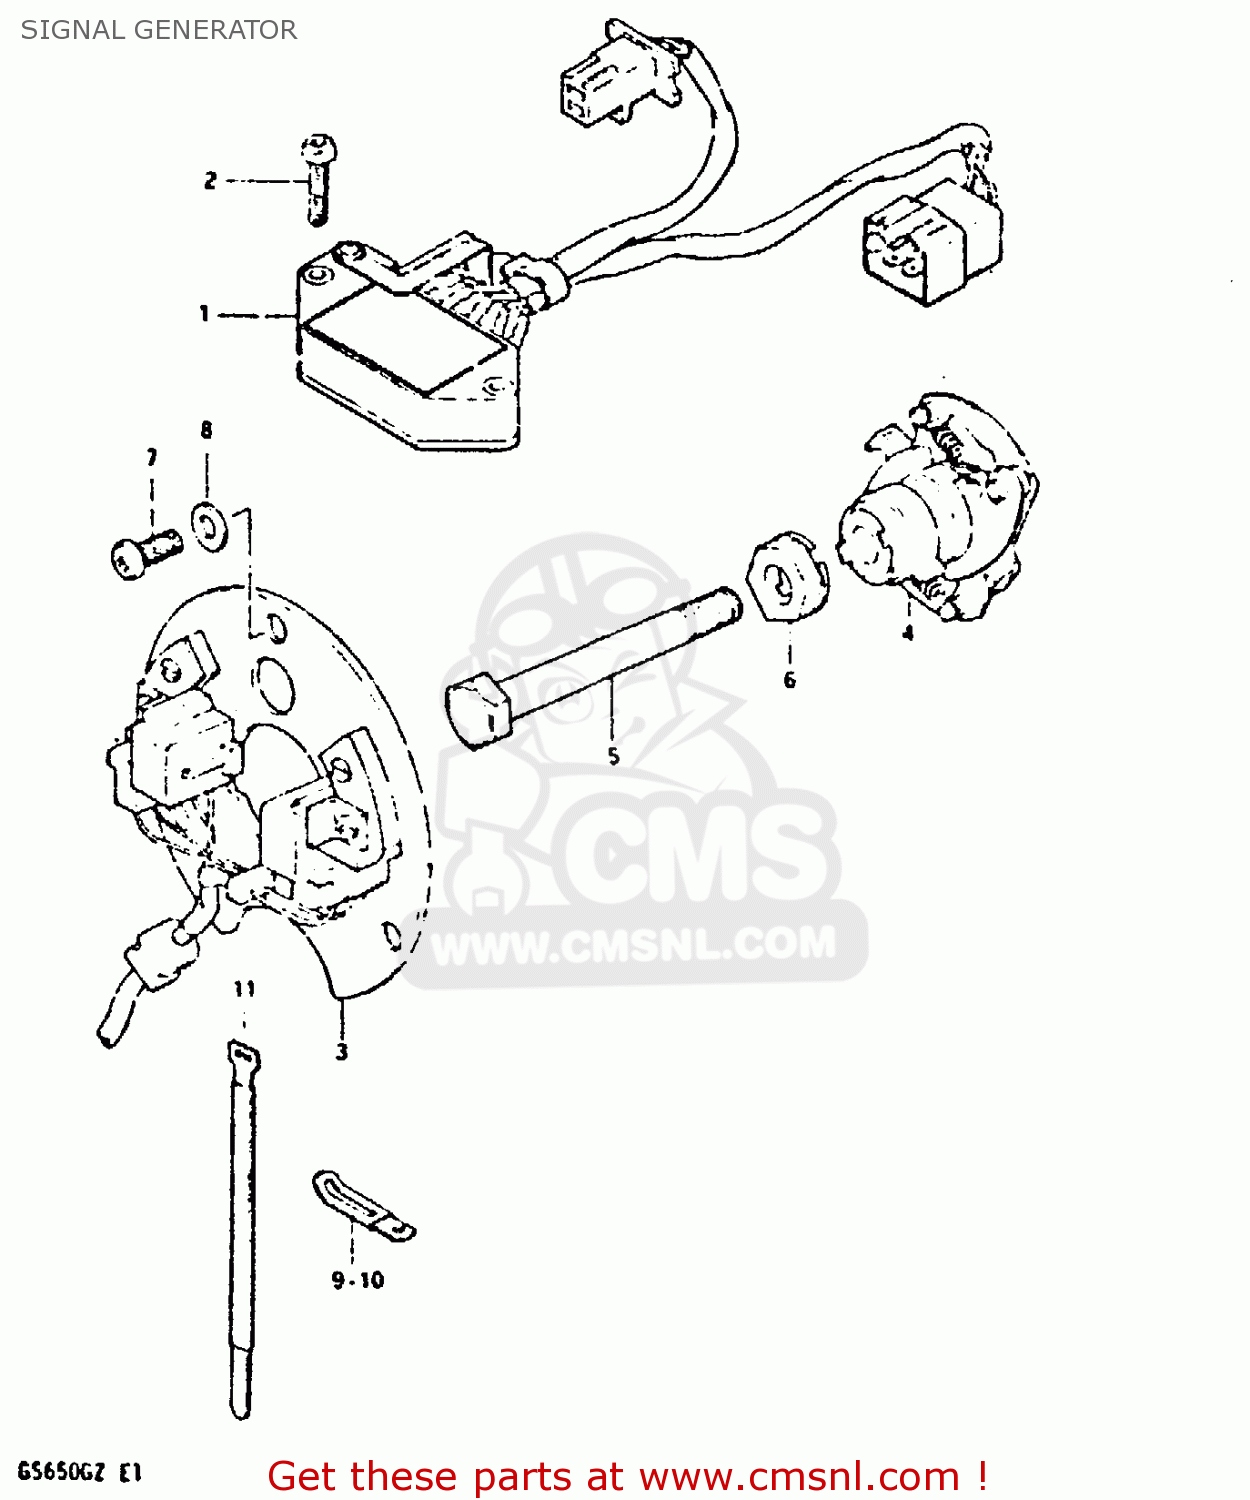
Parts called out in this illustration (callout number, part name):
1	IGNITER UNIT ASSEMBLY
2	SCREW
3	SIGNAL GENERATOR ASSEMBLY
4	GOVERNOR ASSEMBLY
5	BOLT
6	WASHER
7	SCREW(5X12)
8	WASHER
9	CLAMP L:35
10	CLAMP
11	CLAMP
